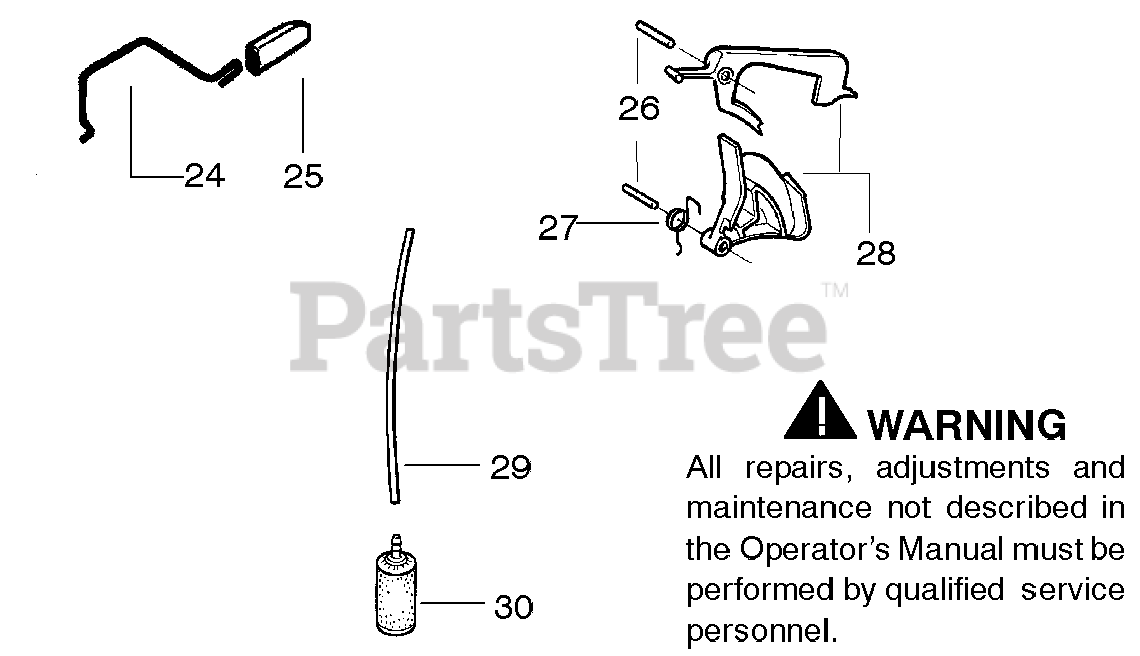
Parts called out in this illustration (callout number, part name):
24	Wire - Throttle
25	Cap - Wire
28	Kit - Throttle Trigger
29	Kit - Fuel line
30	Assy.- Fuel Pickup
